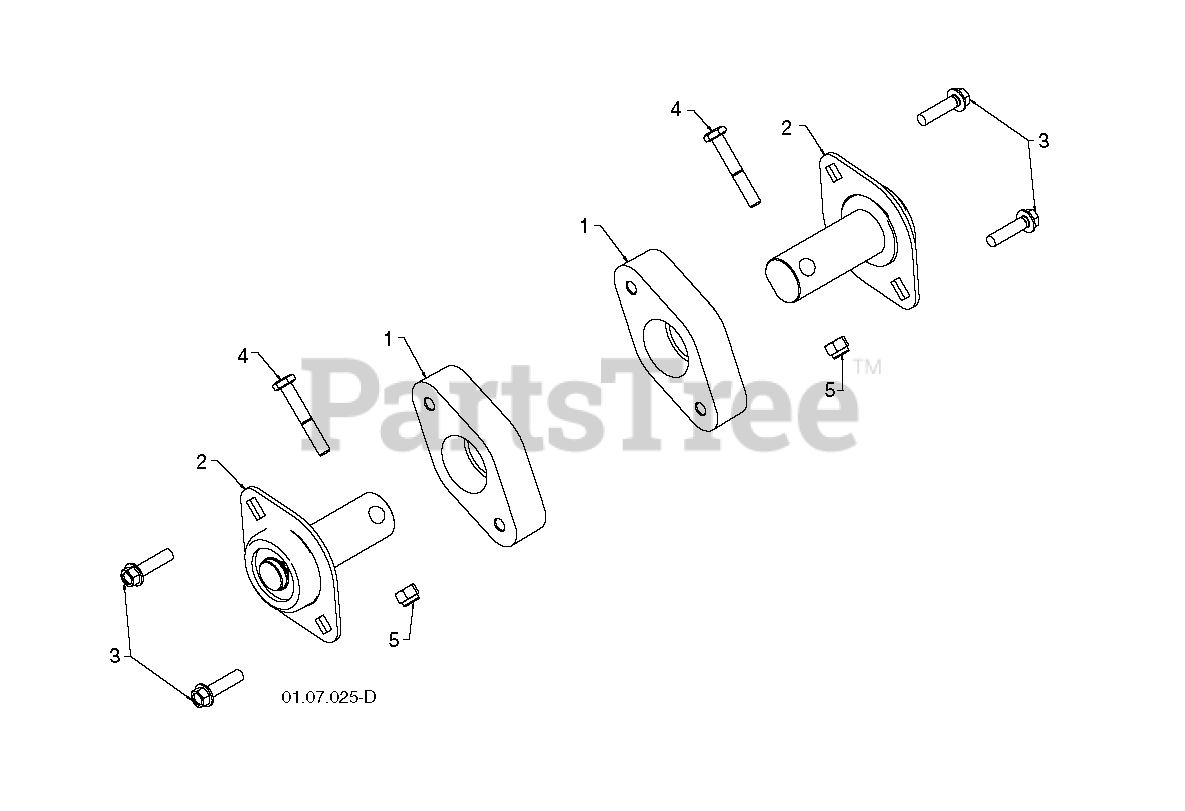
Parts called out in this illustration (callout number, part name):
1	BEARING RETAINER, PLASTIC
2	BEARING.BALL.AUGER.FLAT.
3	SCREW, HEX HD 5/16X1
4	SCREW.HEX.HD1/4-20X
5	LOCKNUT.NYLOC.1/4-20
